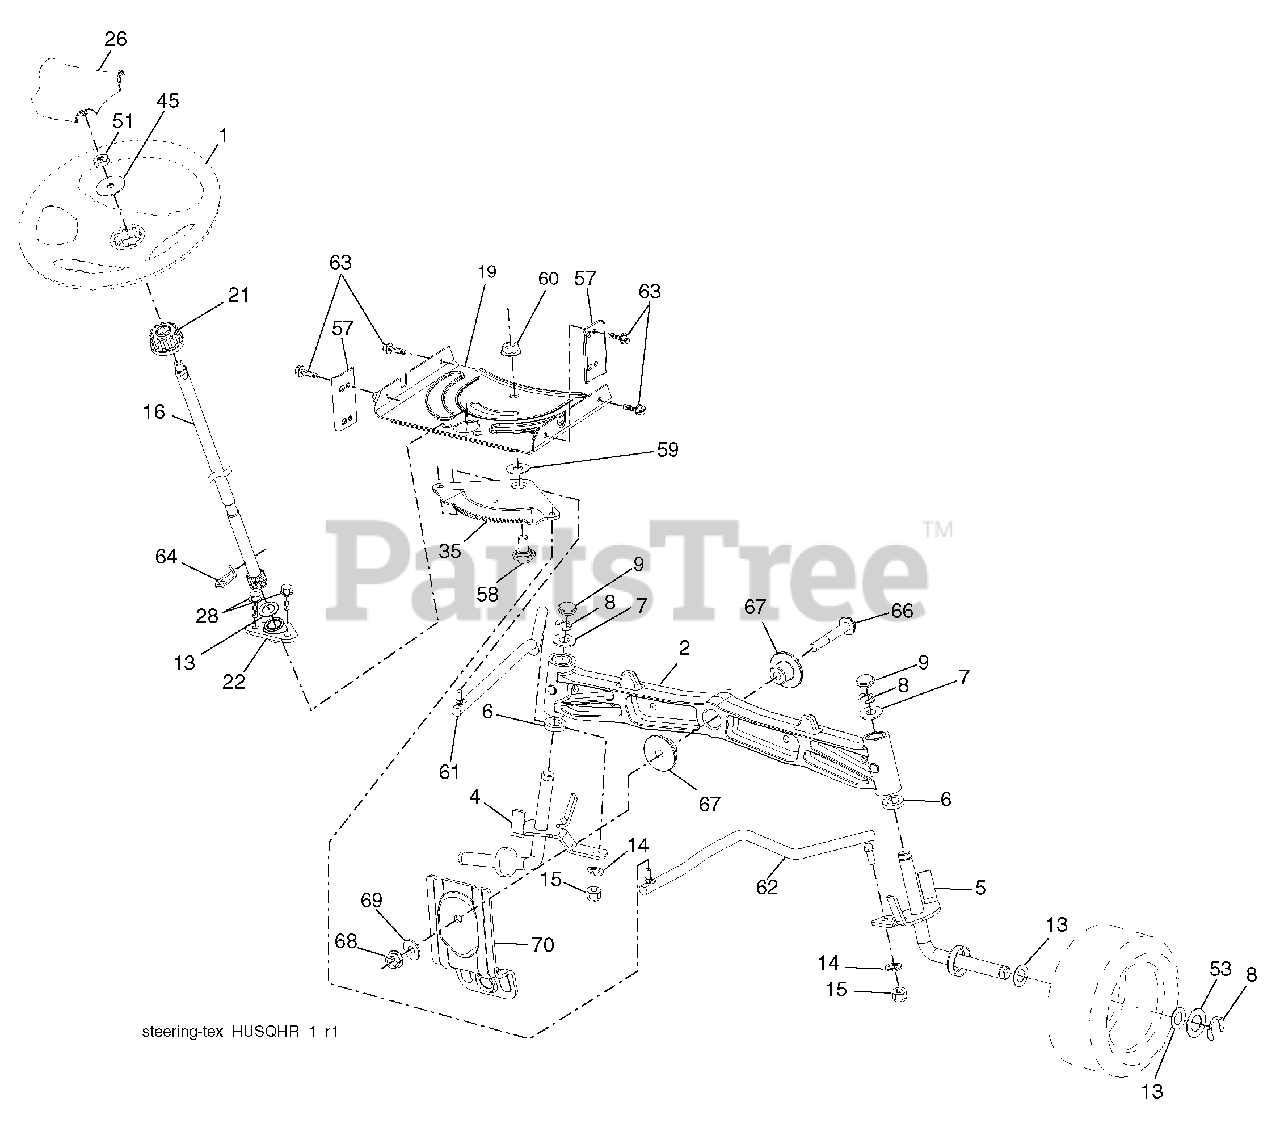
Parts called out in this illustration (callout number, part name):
1	Wheel, Steering
2	Axle Cast Iron
4	Spindle Asm., LH
5	Spindle Asm., RH
6	Washer, Thrust
7	Washer 25/32 x 1-5/8 x 16 Ga.
8	Ring, Klip #T5304-75
9	Cap, Spindle
13	Washer 25/32 x 1-1/4 x 16 Ga.
14	Washer, Lock Hvy Hlcl Spr 3/8
15	Nut, Crown Lock 3/8-24 unf
16	Shaft Steering
19	Plate Steering
21	Adapter, Wheel Steering
22	Steering Support Lower
26	Insert, Wheel Steering
28	Screw 3/8-16 x 3/4
35	Gear, Sector Plate
45	Washer 9/16 ID x 2-3/8 OD 12 Ga.
51	Nut Hex Jam Toplock 1/2-20 unf
53	Washer Hardened .793 x 1.637 x .060
57	Bracket Upstop
58	Bolt Shoulder Sector Pivot CFM
59	Washer Thrust Sector Steering
60	Nut Flange Lock 5/8-11
61	Draglink, LH
62	Draglink, RH
63	Screw 5/16-18 x 3/4
64	Retainer Clip Spring Steering
66	Bolt Hex Fghd 7/16-14 x 3 Serr
67	Bushing PM Front Axle
68	Nut Lock Flange 7/16-14 Gr. 5
69	Washer 1.5 x .505 x .118
70	Bracket Deck Susp. Front
